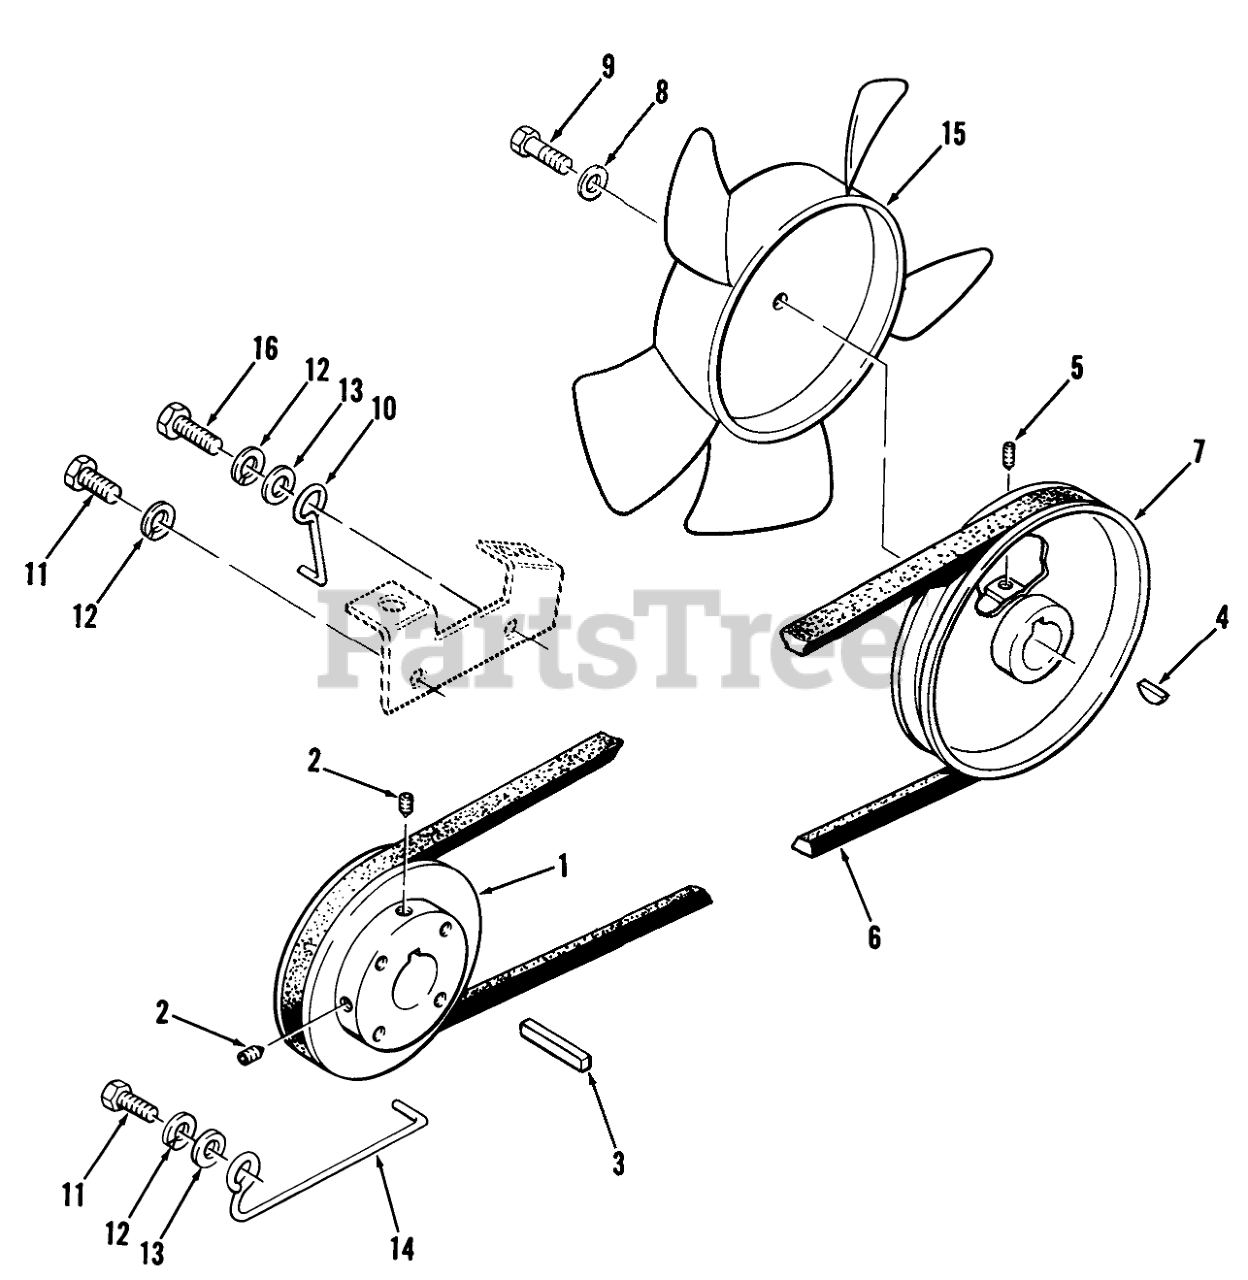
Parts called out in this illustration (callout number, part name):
1	PULLEY
2	Set Screw
4	Key
4	KEY-HI PRO
5	Set Screw
6	V-BELT TRANS DRIVE
6	V BELT
6	Belt-Drive
7	PULLEY
7	PULLEY-TRANSMISSION
8	WASHER
9	H H C S
10	Belt Guide-Top
11	7/16-14 x 1 1/4 Bolt
11	Bolt
12	LOCKWASHER
13	WASHER
13	Washer
14	Belt Guide-Bottom
15	NYLON FAN-L-CW
16	7/16-14 x 1 1/4 Bolt
16	Bolt
